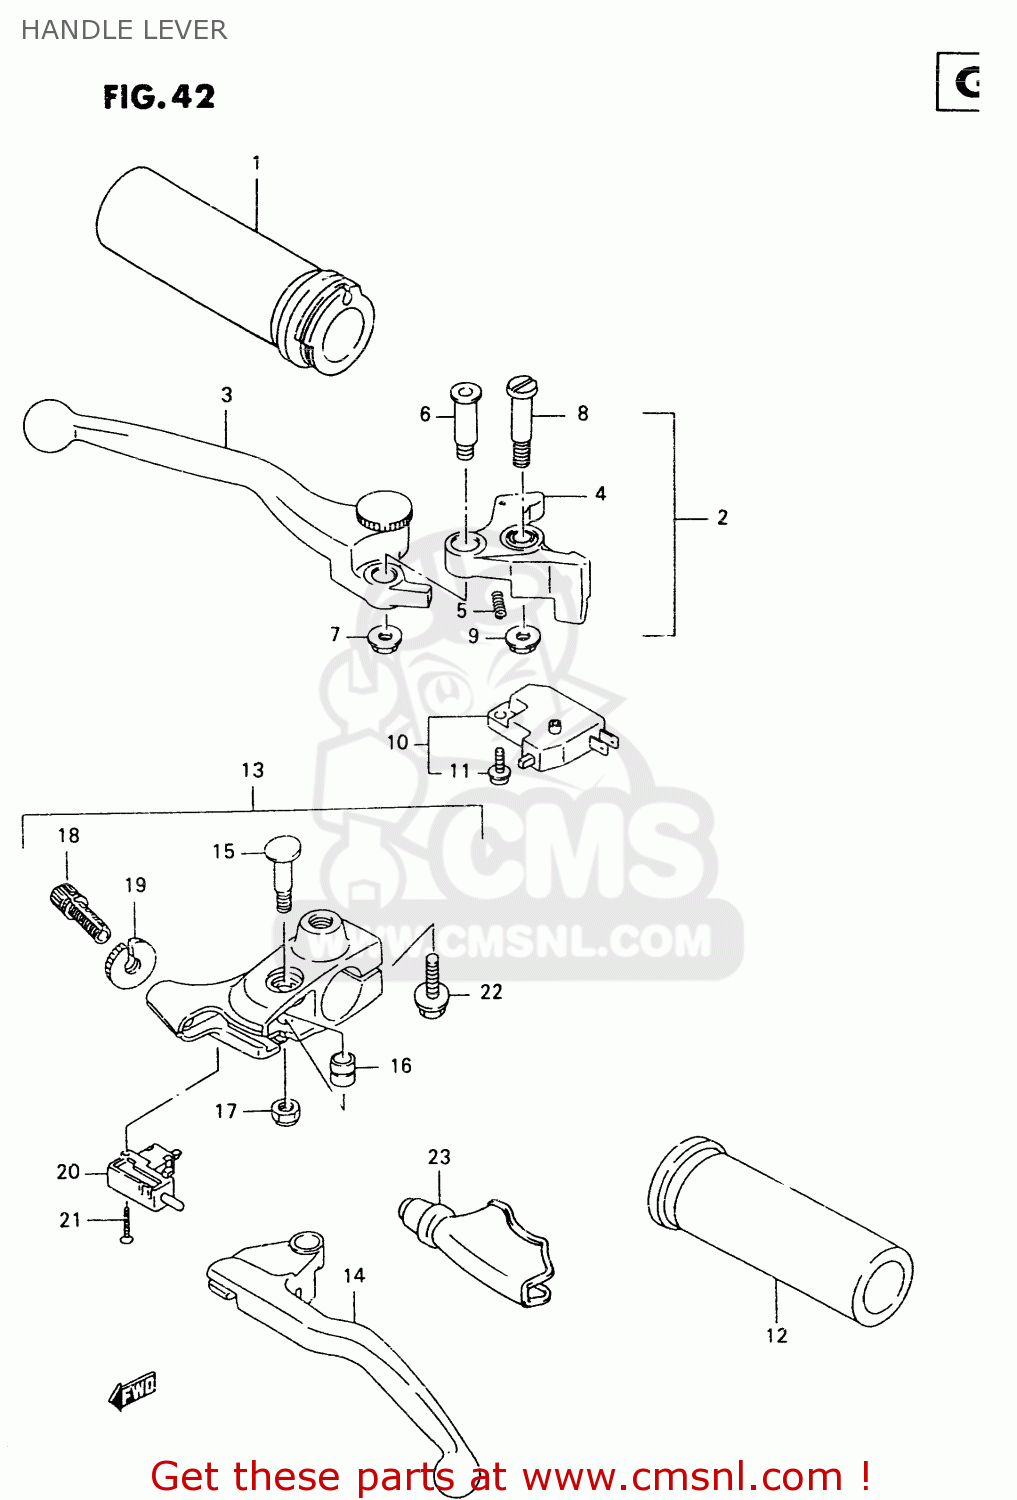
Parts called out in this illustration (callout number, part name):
1	GRIP,THROTTLE
2	LEVER ASSY,BRAKE
3	LEVER,ADJUST
4	KNOCKER
5	SPRING
6	BOLT,LEVER
7	NUT
8	BOLT,LEVER PIVOT
9	NUT
10	SWITCH ASSEMBLY,STOP
11	SCREW
12	GRIP,L
13	LEVER ASSY,CLUTCH
14	LEVER,CLUTCH
15	BOLT,CLUTCH LEVER
16	SPACER,CLUTCH LEVER PIVOT
17	NUT 6MM
18	ADJUSTER,WIRE
19	NUT,LOCK
20	SWITCH,CLUTCH
21	SCREW
22	BOLT
23	COVER,CLUTCH LEVER
